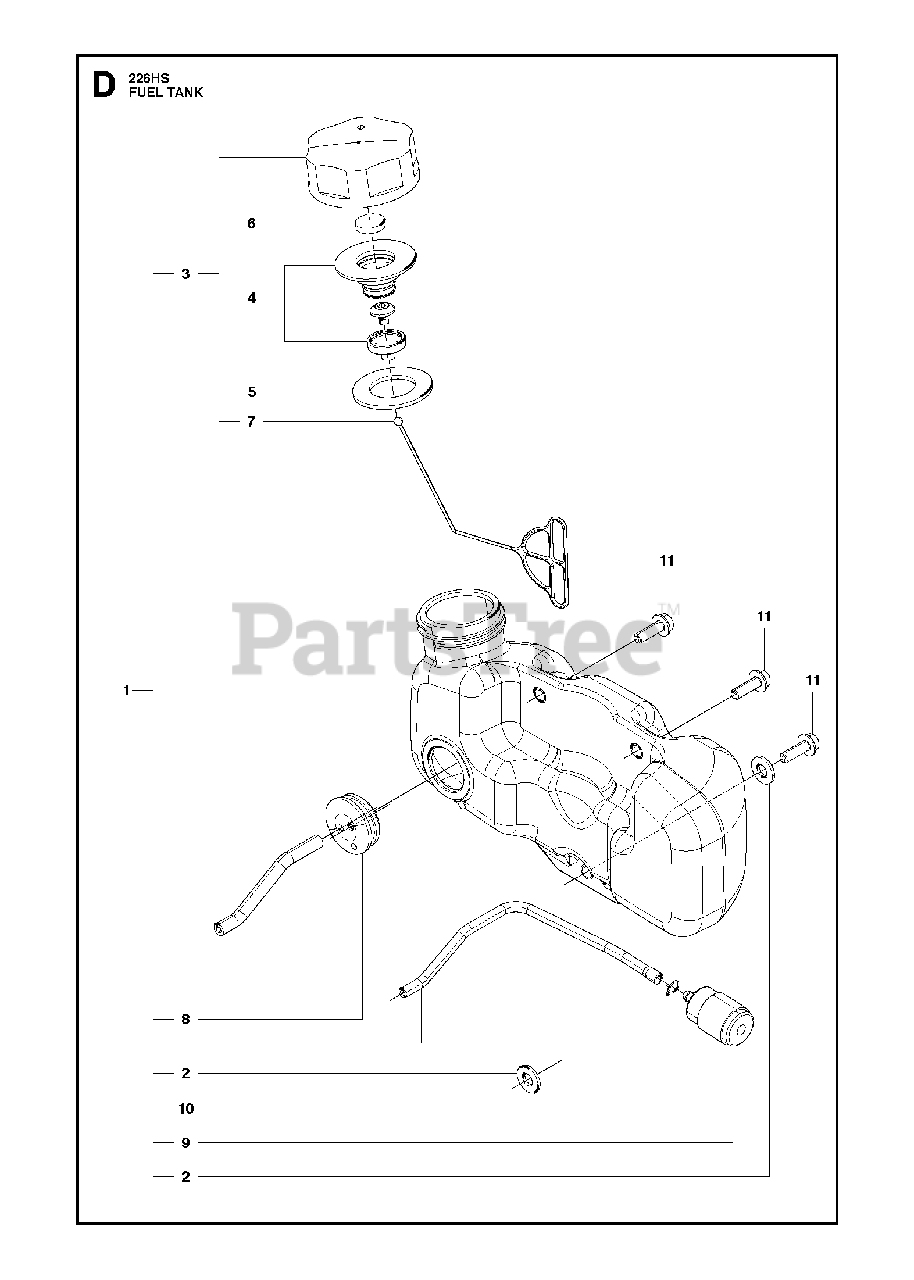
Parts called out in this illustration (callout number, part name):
1	TANK ASSY
2	PACKING
3	CAP A
4	HOLDER-A
5	PACKING
6	FILTER
7	STOPPER
8	PIPE COMP
9	FILTER
10	CLIP
